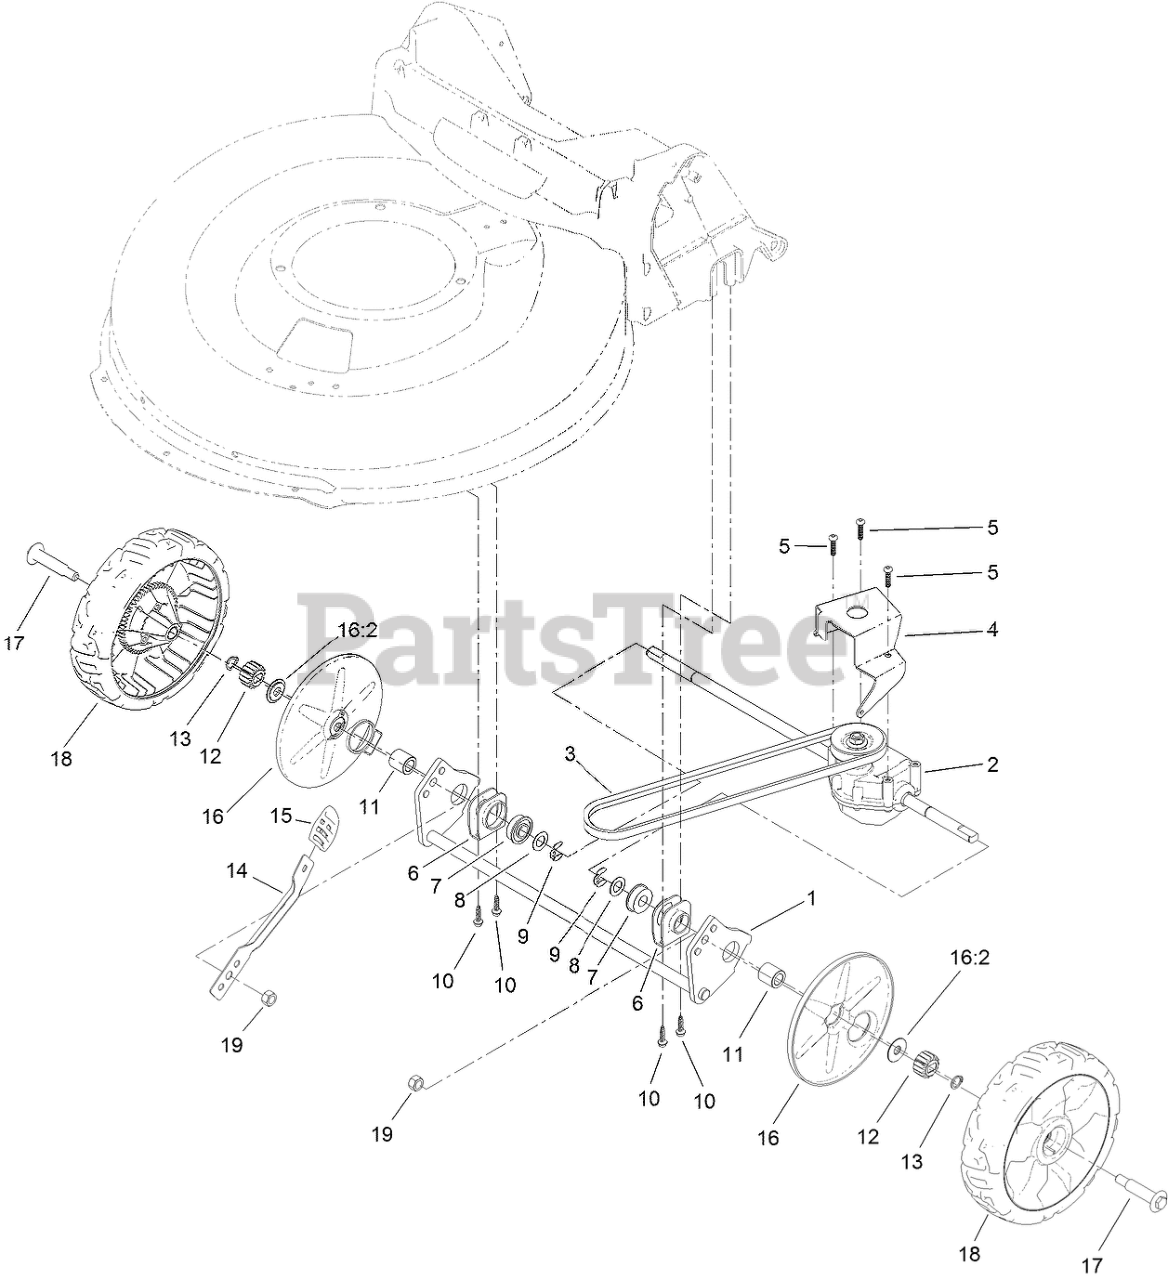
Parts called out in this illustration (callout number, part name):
1	AXLE-REAR
2	TRANSMISSION
3	V-BELT
4	BRACKET-TRANSMISSION
5	SCREW-PLASTITE
6	RETAINER-BEARING
7	BEARING-BALL
8	WASHER-PLAIN
9	RING-RETAINING,CLIP
10	SCREW-HWH
11	BUSHING-SLEEVE
12	GEAR-PINION, 15T
13	RING-RETAINING
14	ARM-SPRING
15	KNOB-LEVER, HOC
16	WHEEL COVER ASM
16:2	WASHER-STEPPED
17	BOLT-SHOULDER
19	NUT-HEX
